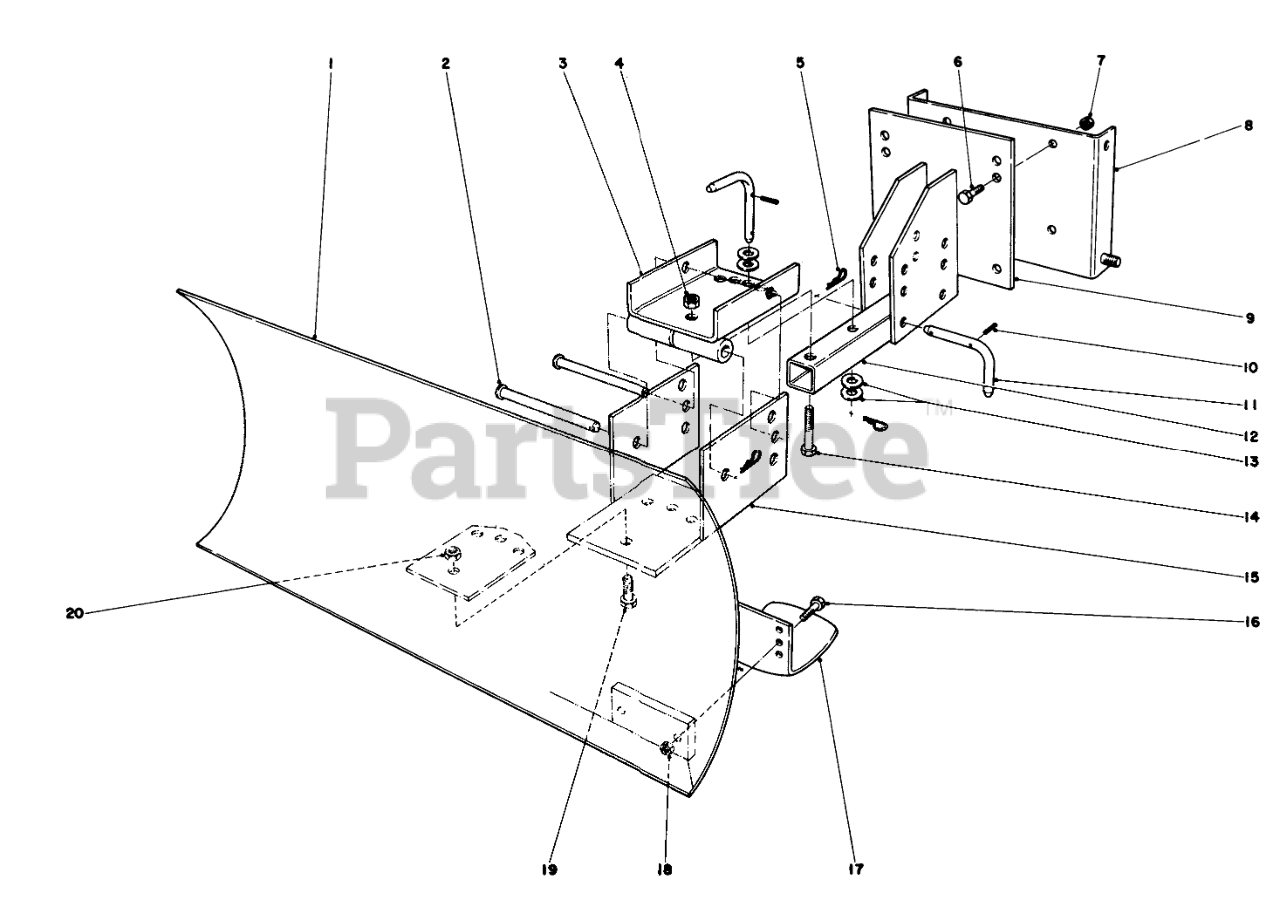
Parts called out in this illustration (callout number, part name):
1	Blade
2	PIN-CLEVIS
3	Swivel Bracket
4	1/2-13 CONELOCK NUT
5	PIN-HAIR
6	SCREW-HH
7	NUT-LOCK, CONE
8	Mounting Plate (Used with 826 & 1132 Units only)
9	Mounting Plate
10	PIN-SPRING
11	Pivot Pin
12	Blade Tongue
13	WASHER-FLAT
14	SCREW-HH
15	Blade Adjustment
16	SCREW-HH
18	NUT-LOCK, CONE
19	SCREW-HH
20	1/2-13 CONELOCK NUT
